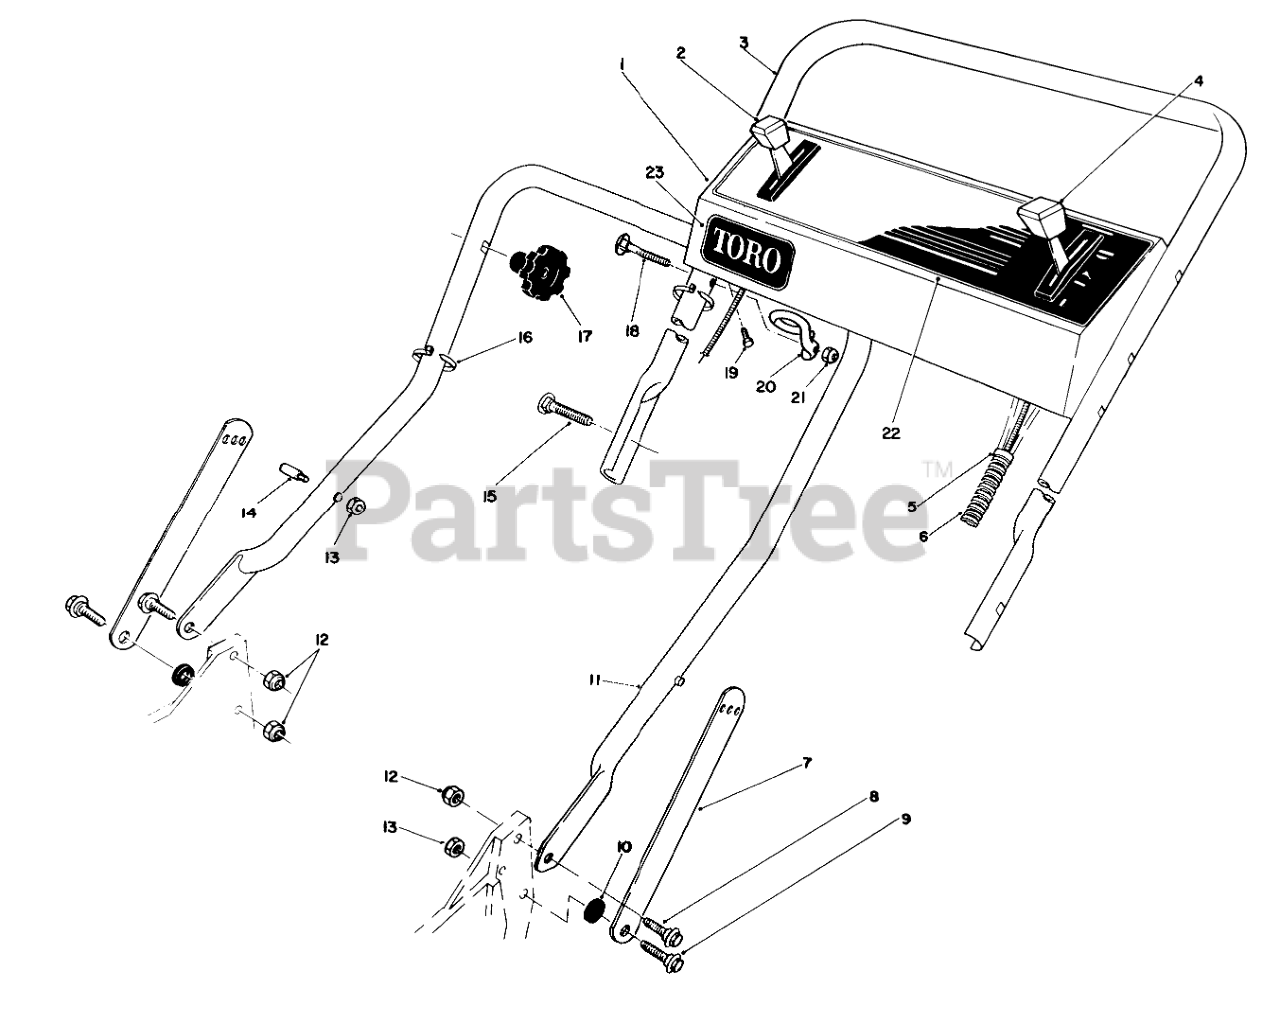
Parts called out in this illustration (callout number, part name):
1	Panel-Control (Incl. Ref. #22)
2	GROUND SPEED CONTROL
3	UPPER HANDLE
4	THROTTLE CONTROL - R&S
5	FITTING-RING
6	CONTROL CABLE COVER
7	Handle Latch
8	SCREW-SHOULDER
9	SCREW-SHOULDER
10	SPACER
11	LOWER HANDLE ASM
12	NUT-LOCK, NI
13	NUT-LOCK, NI
14	HANDLE PIN
15	5/16-18 X 2 HNDLE SCREW
16	TIE-CABLE
18	HANDLE SCREW
19	SCREW-HWHTF
20	Guide
21	NUT-LOCK, NI
22	DECAL - INSTRUCTIONS
23	DECAL
